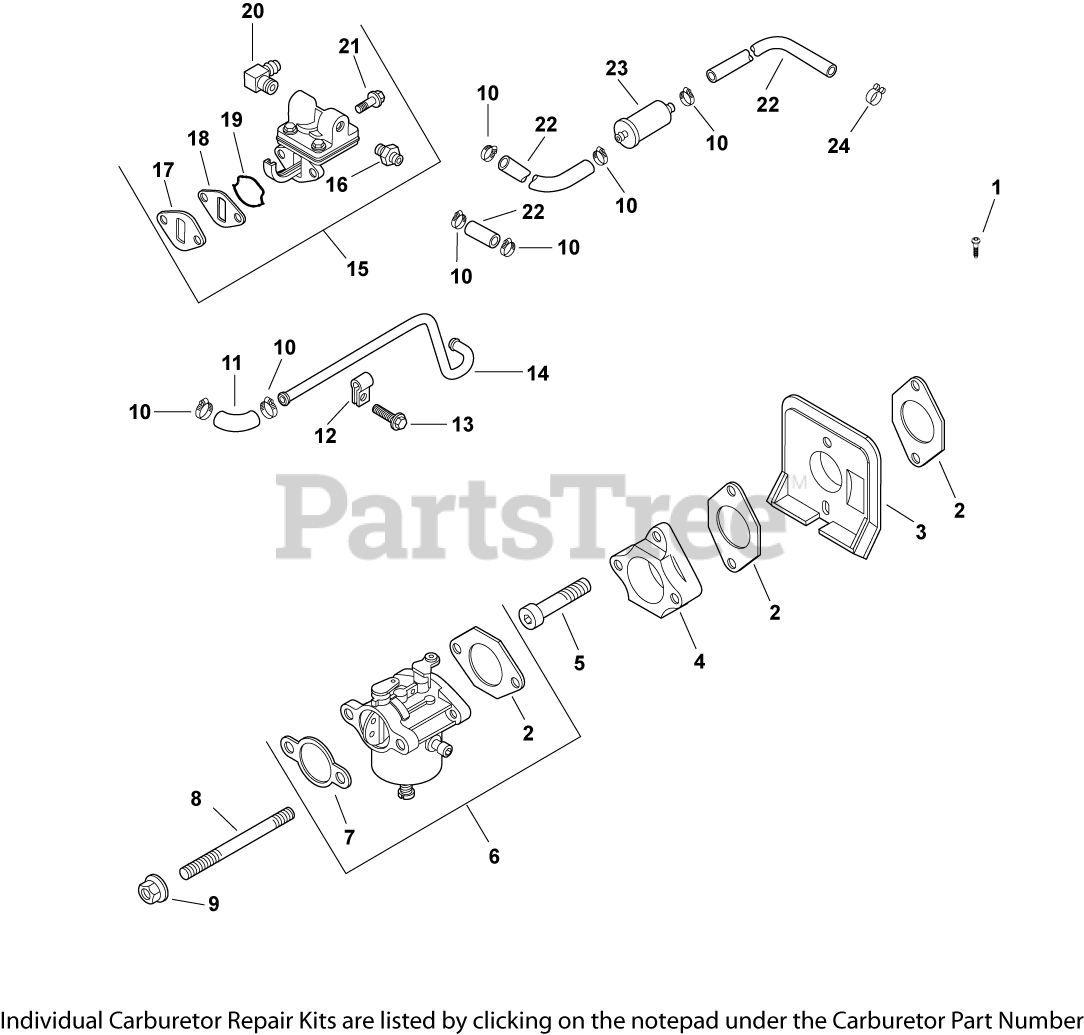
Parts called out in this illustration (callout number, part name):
1	SCREW, LBD SKT M6x1.0x20-(#25086403S)
2	GASKET, CARBURETOR
3	DEFLECTOR, HEAT
4	ADAPTER, CARBURETOR
5	SCREW, SKT CAP M6X1.0X35
6	KIT, CARB W/GASKETS - USE 12 853 169-S
7	GASKET, AIR CLEANER BASE
8	STUD,M6X1.0X116
9	NUT, FLG M6X1.0
10	CLAMP, HOSE (KM)-USE 25 237 31-S
11	HOSE, FUEL LOW-PERMEATION
13	SCREW, FLG THD FRM M5X.8X10
14	LINE, FUEL - DISCONTINUED
15	KIT, FUEL PUMP
16	KIT, STRAIGHT FITTING
17	GASKET, FUEL PUMP
18	SPACER, FUEL PUMP
19	O-RING, FUEL PUMP
20	CONNECTOR, 90 DEG. HOSE
21	SCREW,FLG THD FRM M6X1.0X20-(#25086396S)
22	HOSE,LW PERM.FUEL 24.00"-USE 25 111 81-S
23	FILTER,FUEL 51 MICRON (FUEL PUMP)
24	CLAMP, BAND SPRING HOSE-(#2523737S)
